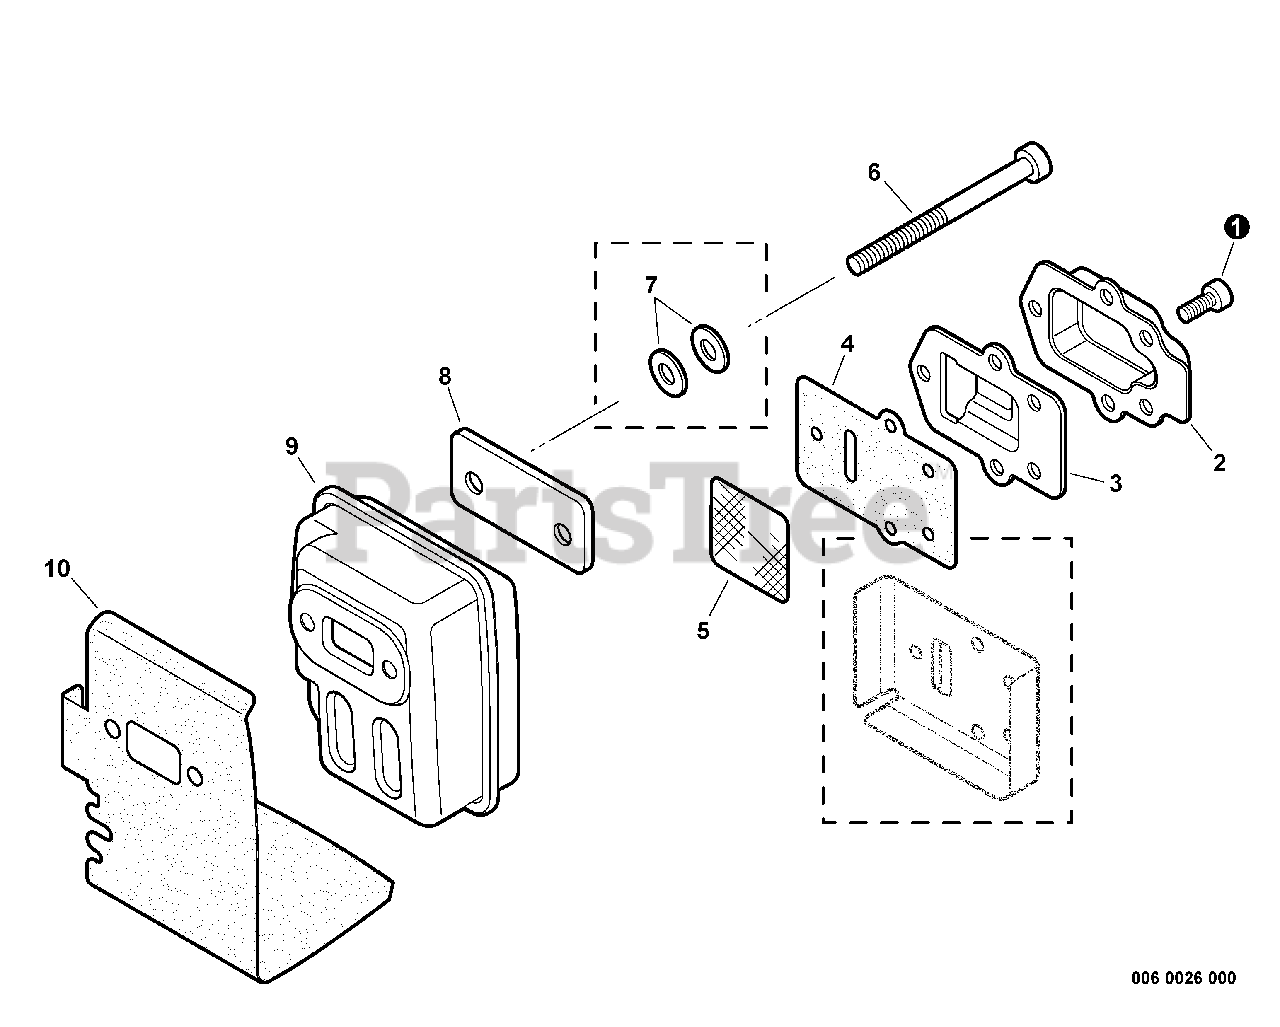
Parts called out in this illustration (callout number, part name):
1	SCREW 4×10
2	DEFLECTOR, EXHAUST
3	GUIDE, EXHAUST
4	GASKET, EXHAUST
5	SCREEN, SPARK ARRESTER
6	BOLT 5×55
7	CONICAL WASHER
8	PLATE, EYE
9	MUFFLER
10	HEAT SHIELD, EXHAUST
